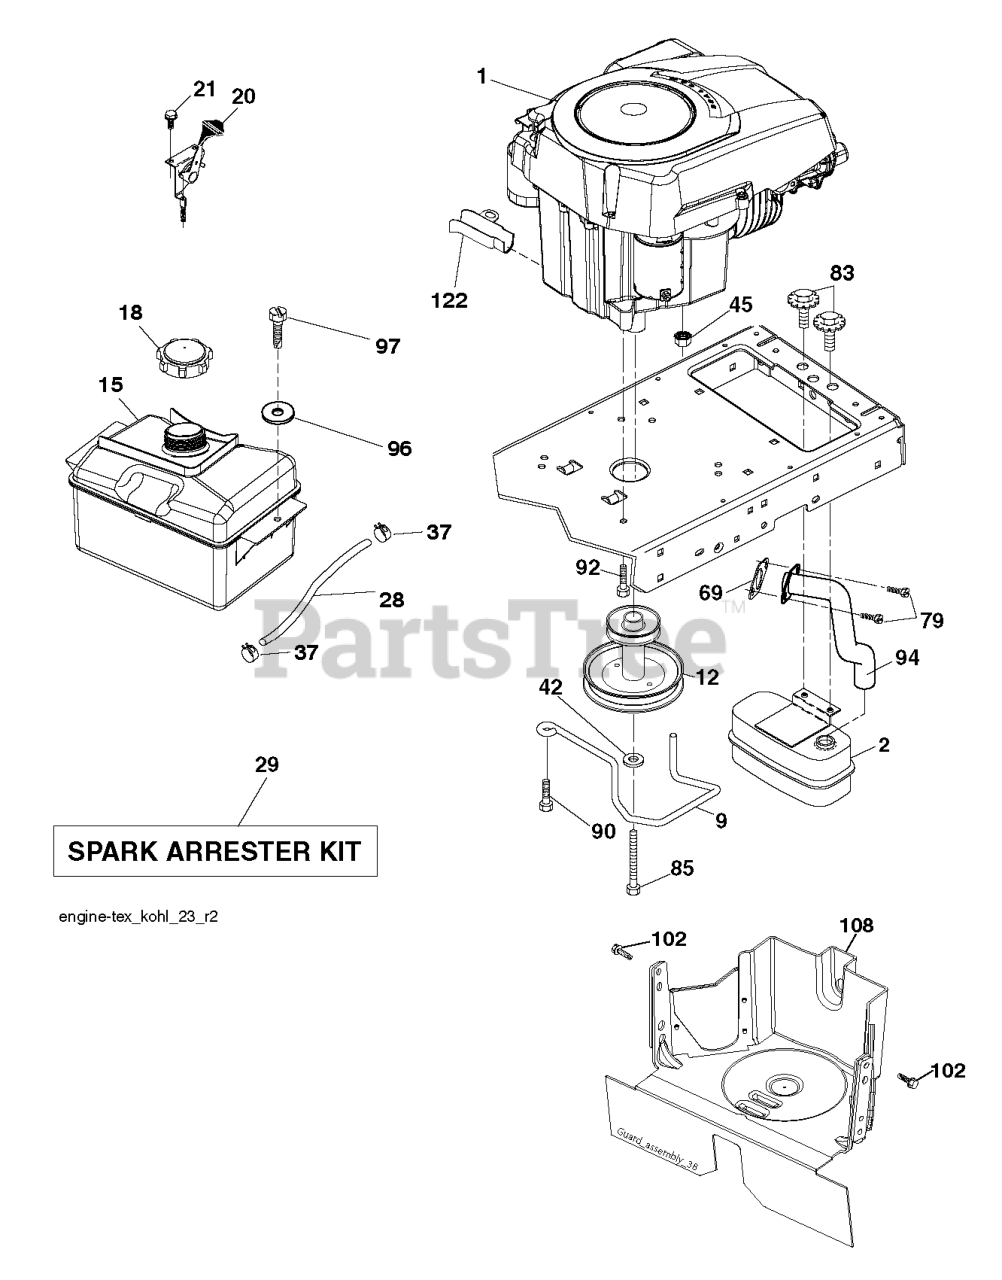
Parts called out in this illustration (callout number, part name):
2	MUFFLER.SINGLE.CYL.KOHL/B&S
9	KEEPER.BELT.ENGINE.4.2
12	PULLY ENGINE
15	RP TANK FUEL FRT 1.5 GAL
18	CAP ASM.FUEL.2.25"FR.
20	CONTROL.TH/CK.C.
21	SCREW.#10 X 0.750.BOS
28	LINE.FUEL.20
29	KIT.SPARK ARRESTOR 794945 B&S
37	HOSE CLAMP
42	LOCKWASHER
45	NUT
69	GASKET.EXHAUST.KOHLER
79	SCREW.SOCKET HD.5/16-1
83	BOLT.5/16-18UNCX3/4 W/SEMS.BLK
85	BOLT HEX 7/16-20X4-1/4"
90	SCREW 3/8-16X1
92	SCREW 3/8-16X1
94	RP.TUBE.EXHAUST.KOHL.COURAGE
96	WASHER
97	SCREW HEXWSHR 1/4-20X3/4
102	SCREW 5/16-18X1
108	COVER PULLEY
122	EXTENSION DRAIN OIL
